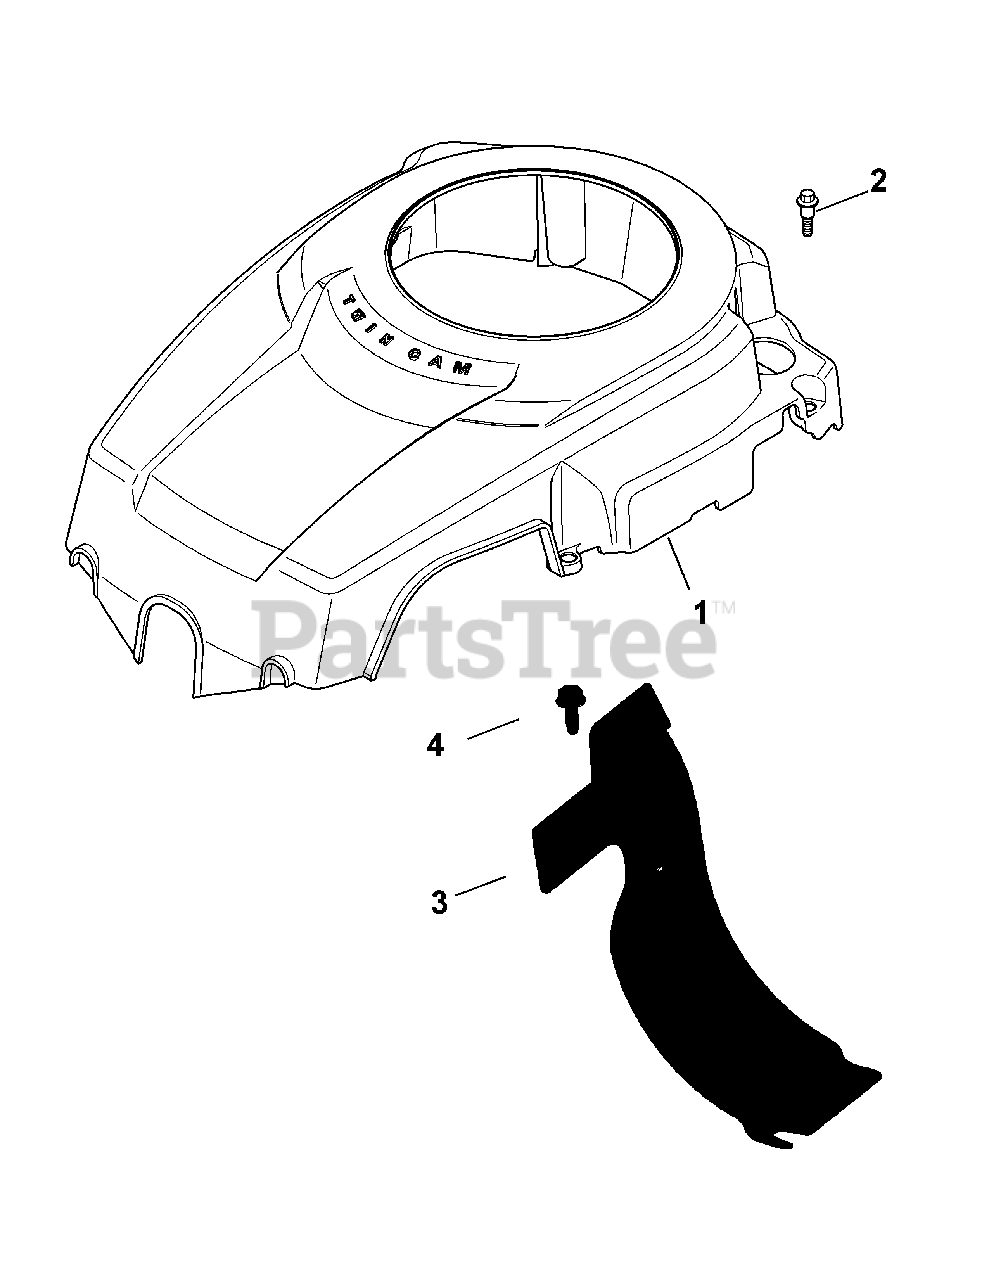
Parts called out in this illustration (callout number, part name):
1	Blower Housing Kit (Inc. 3)
2	Shd. Thd. Frm. Screw, M6 X 1 X 26
3	Baffle Baarrel
4	Screw-Hex Flange M6 x 1.0 x 16
